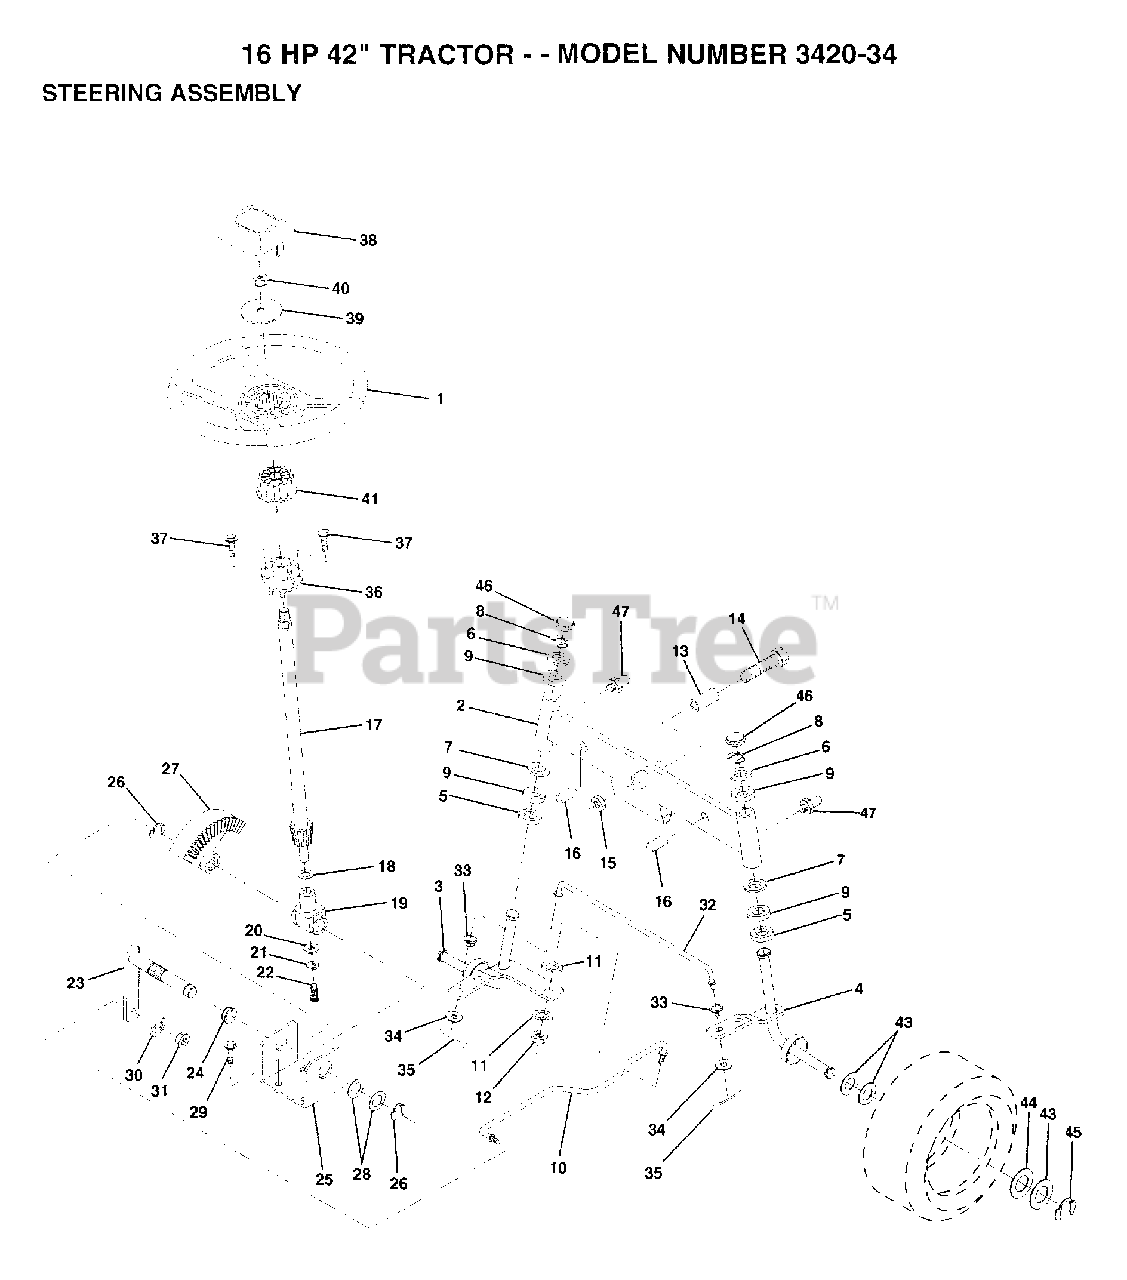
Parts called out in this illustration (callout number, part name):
3	SPINDLE LH
4	SPINDLE RH
5	WASHER .T
6	WASHER
7	WASHER
8	RING
9	COL. SRTG. BEAR.
11	LOCKWASHER
13	BEARING
14	BOLT HEX 5/8-11
15	"NUT-LOC,FLANGE LT"
16	AXLE PIN
17	STEERING SHAFT
18	THRUST WASHER
19	SUPPORT.SHAFT
21	LOCKWASHER
22	"SCREW,SPECIAL"
24	NYLINER T
25	"BRKT,STEERING"
26	RING
27	GEAR SECTOR
28	WASHER .T
29	SCREW
30	LOCKWASHER
32	TIE ROD
33	BUSHING.DRAGLINK
34	WASHER
35	COTTER PIN
38	"INSERT,STR WHEEL"
39	WASHER
41	ADAPTER LT
43	WASHER
44	WASHER
45	RING
46	CAP
47	ZERK M
